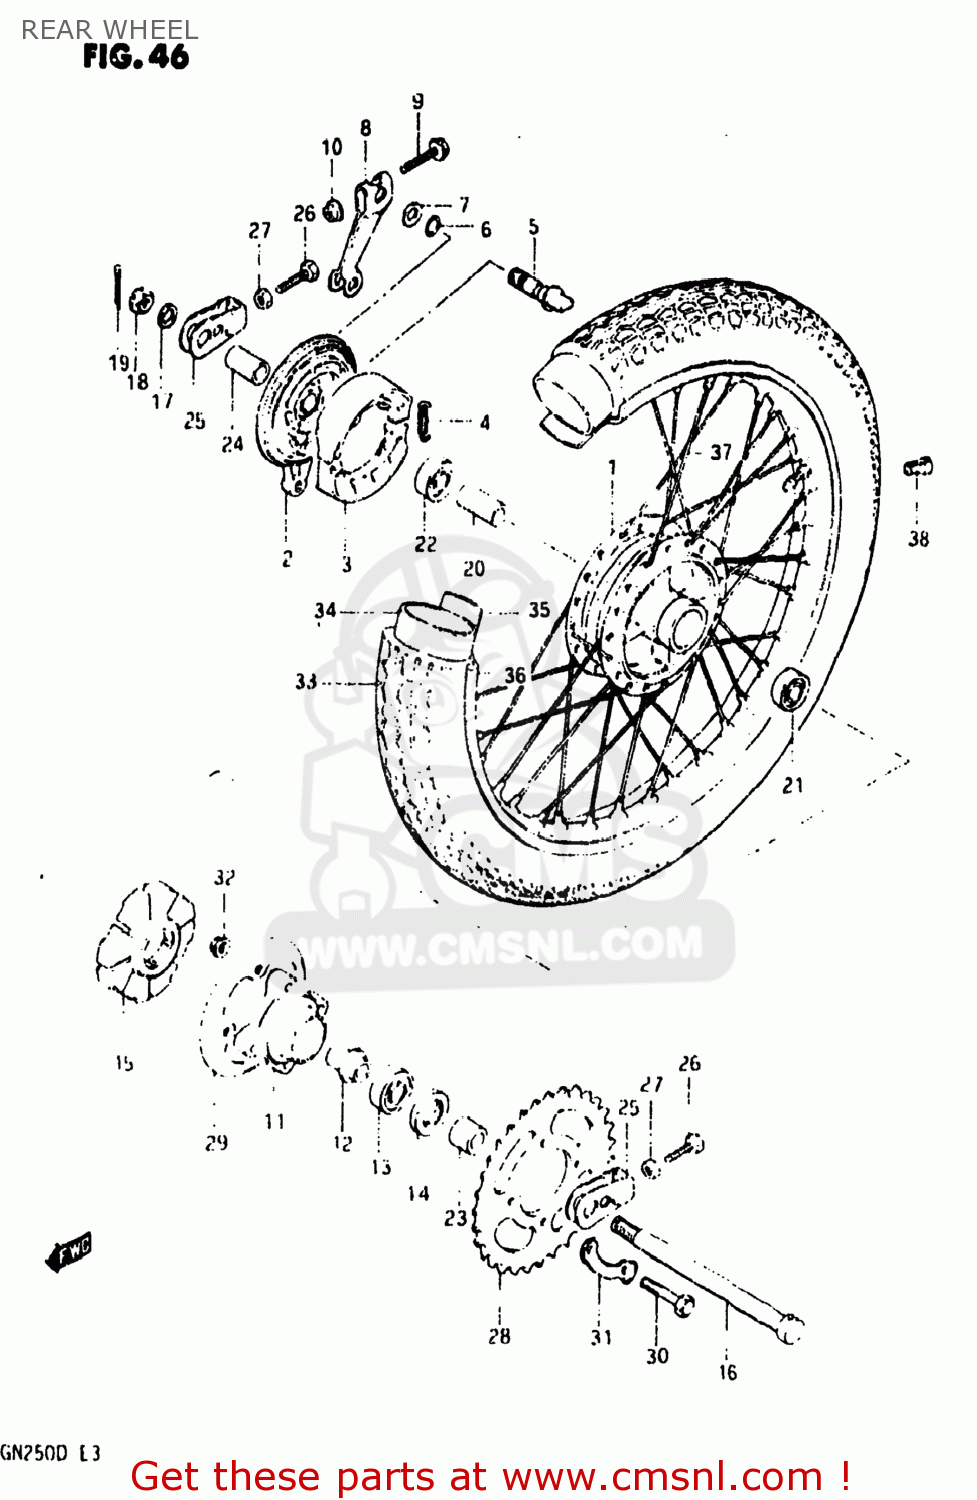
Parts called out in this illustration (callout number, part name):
1	HUB,REAR WHEEL
2	PANEL,REAR BRAKE ANCHOR
3	SHOE,BRAKE
4	SPRING(L:34)
5	CAM,FRONT BRAKE
6	O-RING (D:2.4 ID:13.8)
7	WASHER (14.5X22X1.6)
8	LEVER,RR BRAKE CAM
9	BOLT
10	NUT
11	DRUM,RR SPROCKET MOUNTING
12	RETAINER,RR SPROCKET DRUM
13	Bearing
14	SEAL,OIL(28X47X7)
15	ABSORBER ASSY,HUB SHOCK
16	AXLE,REAR
17	WASHER
18	NUT
19	COTTER PIN
20	SPACER(15.3X21.7X63)
21	BEARING
22	BEARING, RH
23	SPACER(15X28X24.8)
24	SPACER(15X22X46.8)
25	ADJUSTER,CHAIN
26	BOLT 8X50
27	NUT
28	SPROCKET,REAR
29	GUIDE,RR SPROCKET CHAIN
30	BOLT 10X40
31	WASHER
32	NUT
33	TIRE
34	TUBE ASSY,WHEEL,INNER 4.60-16
35	PROTECTOR,INNER TUBE
36	RIM,RR WHEEL(215X16)
37	SPOKE SET,REAR WHEEL
38	BALANCER,WHEEL (B)
